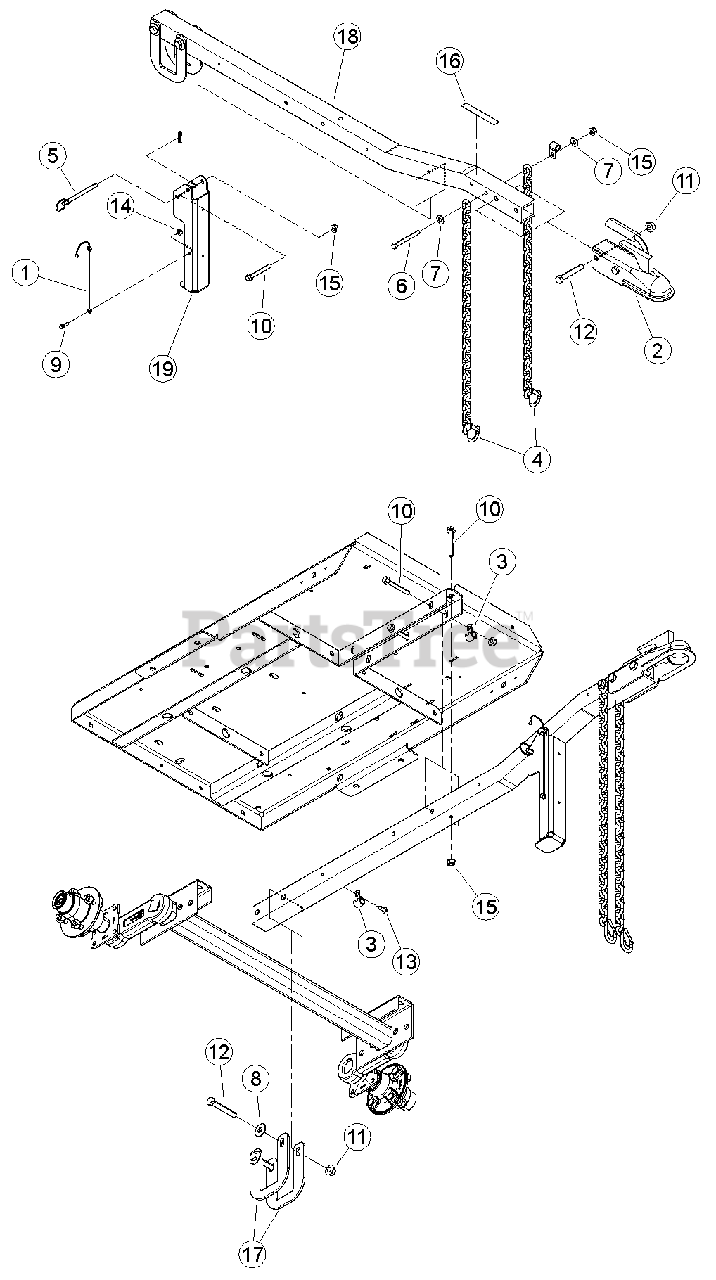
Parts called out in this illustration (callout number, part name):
1	LANYARD, NYLON
2	COUPLER, 50 MM BALL
3	CLAMP, 9/16 COATED
4	CHAIN, SAFETY 5000 LB W/ LATCH
5	PIN, 3/8 HITCH
6	BOLT, 3/8 X 3-1/2" HEXHD GR5 ZP
7	WASHER, 3/8" FLAT ZP
8	WASHER, 1/2" FLAT ZP
9	BOLT, 1/4-20 X 3/4 HWH GR5 CZP
10	BOLT, 3/8 X 3 FLANGE NC
11	NUT, 1/2-13 NYLOCK FLANGE
12	BOLT, 1/2 X 3-1/4 HCS GR5 ZP
13	SCREW, 11/32 X 7/8 HWH AB THREAD ZP
14	NUT, 1/4-20 NYLOCK FLANGE
15	NUT, 3/8-16 NYLOCK FLANGE
16	DECAL, HITCH LOAD
17	PLATE, HITCH SADDLE
18	POLE, C/S HITCH
19	WELDMENT, STAND JACK
